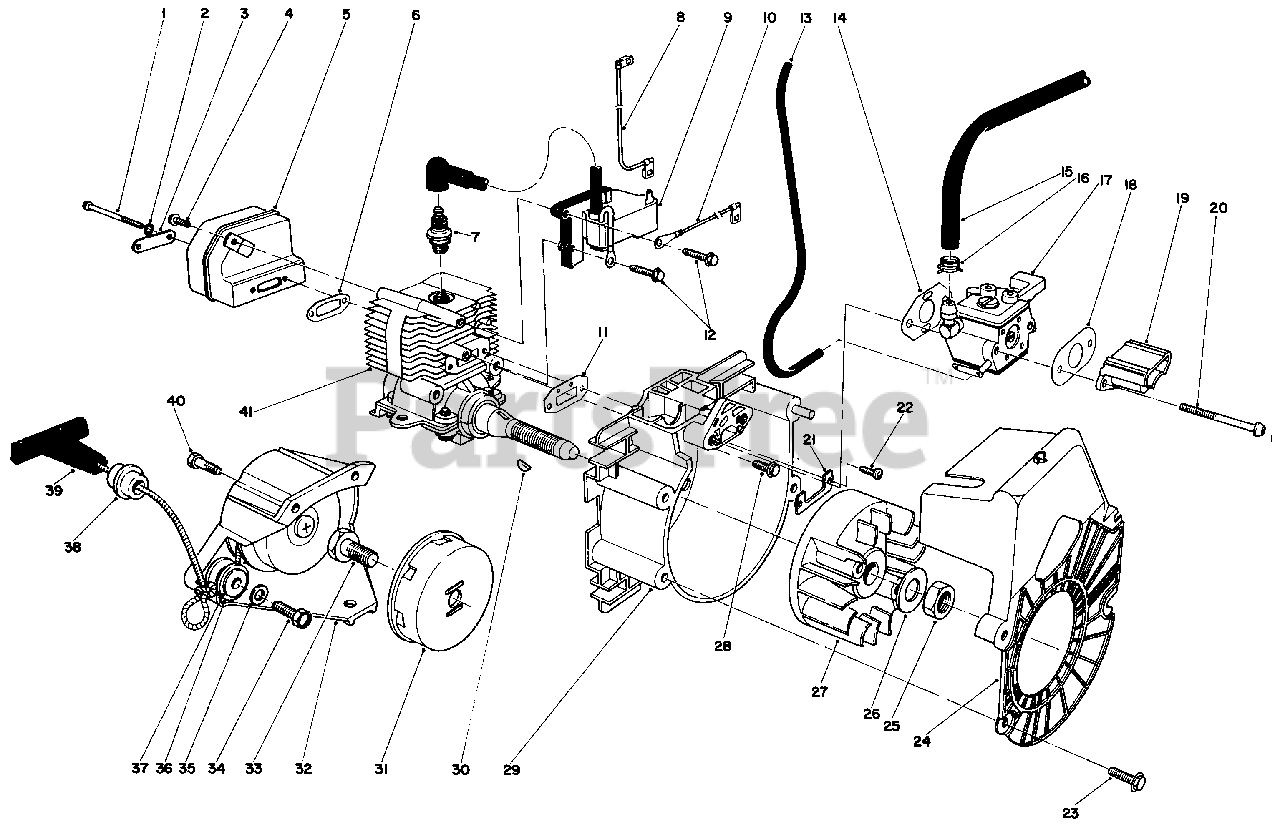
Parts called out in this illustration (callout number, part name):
1	Screw, Muffler
2	Lockwasher
3	Stress Plate, Muffler
4	Screw, Muffler Tab
5	Muffler Assembly
6	Gasket, Exhaust
7	Spark Plug
8	Wire Assembly-Coil
9	CDI Module, Speed Limiting
10	Wire Assembly-Ground
11	Gasket, Intake
12	Screw, CD I Mount
13	Hose, Primer
14	Gasket, Carburetor
15	Hose Fuel
16	Clamp, Fuel Line
17	Carburetor
18	Gasket, Choke/Spitback Cup
19	Spit Back Cup
20	Screw, Carburetor
21	Plate, Stress
22	Screw, Intake
23	Screw, Shroud
24	Cooling Shroud
25	Nut, Flywheel
26	Washer, Flywheel
27	Flywheel
28	Screw, Backing Plate
29	Backing Plate Assembly
30	Key, Flywheel
31	Cup, Starter
32	Starter Assembly (Incl. Ref. #34-39)
33	Screw, Starter Cup
34	Screw, Idler Pulley
35	Washer, Brake
36	Idler Pulley (Incl. Ref. #37)
37	Bushing
38	Guide, Rope
40	Screw, Starter Assembly
41	Short Block
